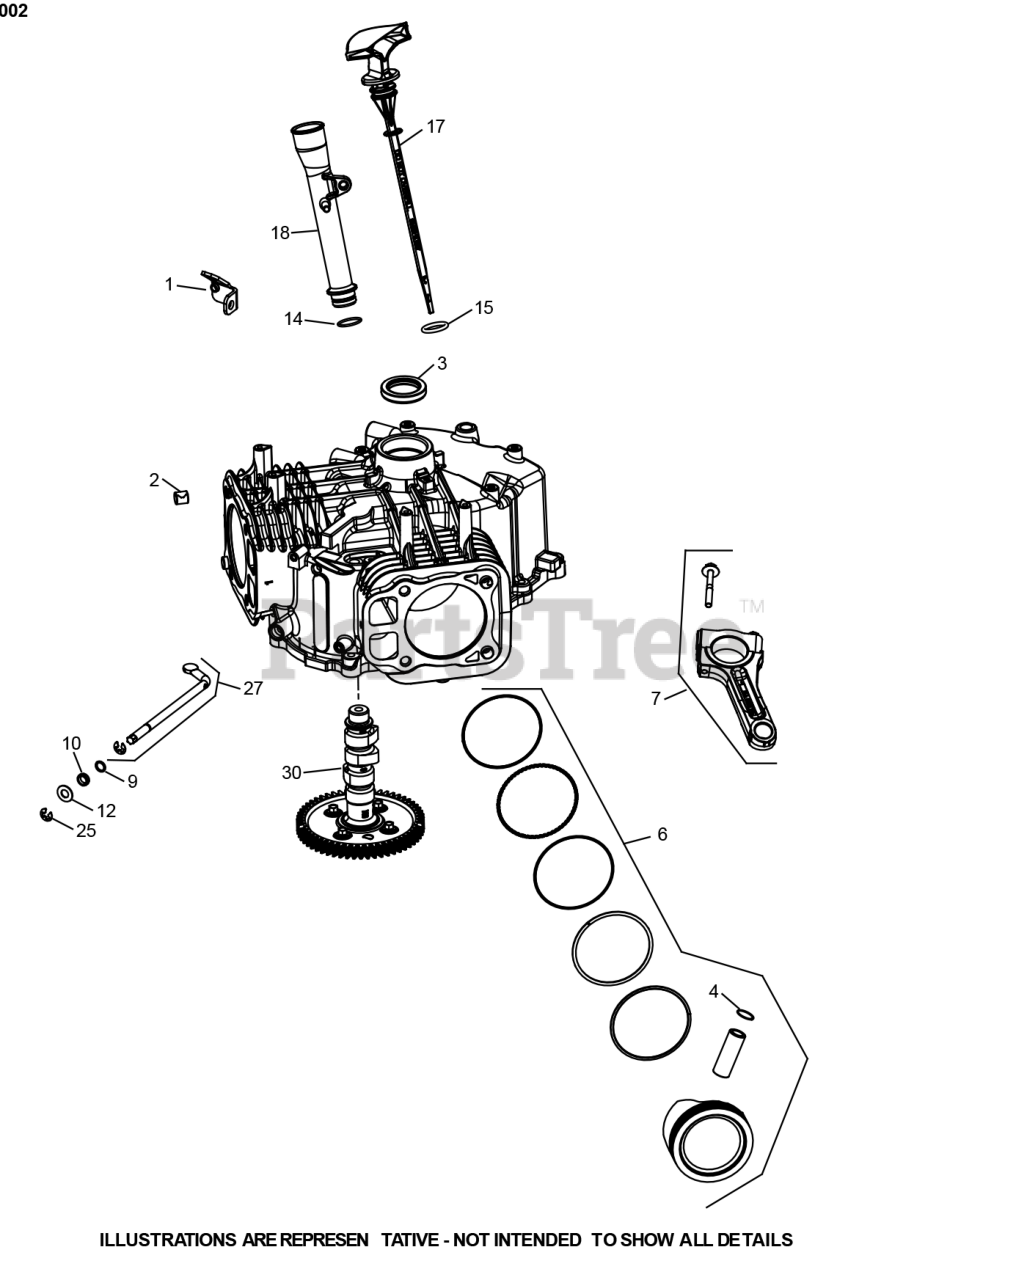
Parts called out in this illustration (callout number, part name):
1	BRACKET-OIL FILL TUBE
2	PIN-SPLIT DOWEL
4	RETAINER-PISTON
6	PISTON KIT (STD)
7	CONNECTING ROD ASSEMBLY
9	WASHER-1/4 FLAT
12	WASHER-9MM FLAT
15	O-RING DIPSTICK
18	DIPSTICK TUBE
25	GOVERNOR SHAFT RETAINER CLIP
27	CROSS CARBURETOR SHAFT KIT
